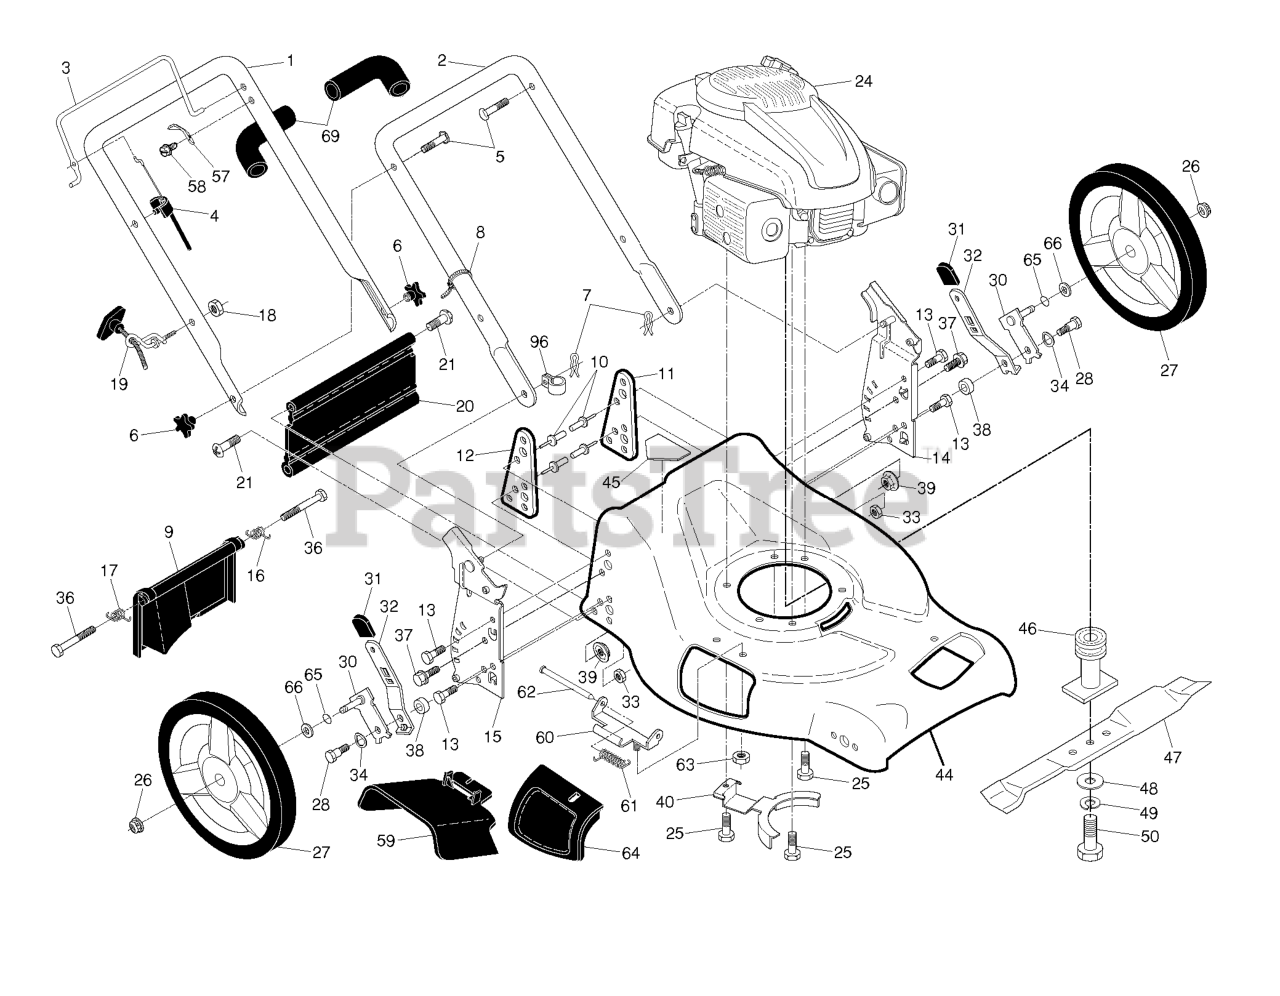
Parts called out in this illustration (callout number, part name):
1	HANDLE.ASM.GRY.W/GRIP
2	LOWER HANDLE
3	BAIL.DSTRT.AW.CREAS.ORAN
4	RP CABLE.MZR.54.10.SNAP.IN.RT
5	BOLT, HANDLE 5/16-18X1.75
6	KNOB.HANDLE.PLASTIC.STAR.BLACK
7	HAIRPIN COTTER
8	TIE GUIDE
9	REAR DOOR ASSEMBLY
10	RIVET BLIND
11	SUPPORT BRACKET LH
12	BRACKET.SUPRT.RH.21.FWGD
13	SCREW 14-20 X 5/8
14	RP BRACKET.ASM.HNDL/HW.LT.21.
15	BRACKET.ASM.HNDL/HW.RT.21.PNT
16	SPRING.REAR.DOOR.EZ.21.LT
17	SPRING.REAR.DOOR.EZ.21.RT
18	NUT
19	RB GUIDE.ROPE.STD.BLK.ZIN WSL
20	SKIRT.REAR.21 FWGD.BLACK
21	HINGE SCREW
25	BOLT 3/8-16X1-1/8
26	NUT.HEX.FLANGE.3/8-16.LOCKNUT
27	WHEEL ASSY
28	SHOULDER BOLT 5/16-18
30	ARM.ASM.AXLE.REAR.5/9.POS.BZP
31	SELECTOR KNOB
32	SELECTOR SPRING
33	NUT.FLANGE.5/16
34	WASHER.CURVED.CYLINDRICAL
37	BOLT.FIN.HEX.5/16-18X3/4
38	SPACER.HEIGHT.ADJUSTER
39	NUT.71038.31-18.HEX.NYLOCK
40	BRACKET.KEEPER.BELT
44	HOUSING.21.FWD.ORANGE.WALK
45	DANGER DECAL
46	RP ADAPTER.BLADE.25MM.21F
47	BLADE.21.PUSH/RWGD/FWGD
48	WASHER,HARDEN
49	LOCKWASHER
50	SCREW, HEX HD 3/8-24 X 1-3/8
57	BRACKET UPSTOP
59	DEFLECTOR.CLIPPIN.21.FGD
60	BRACKET.ASM.HINGE.21.FWGD.
61	SPRING.TORSION
62	ROD.HINGE.21
63	LOCKNUT.NYLOC.1/4-20
64	DOOR.MULCH.21.REAR.FWGD
65	O-RING..070X.487.NEOPRENE
66	WASHER.FLAT.1/2
69	GRIP.HANDLE.FOAM.WIDE.(1 SIDE)
96	CLIP.CABLE.BLK
